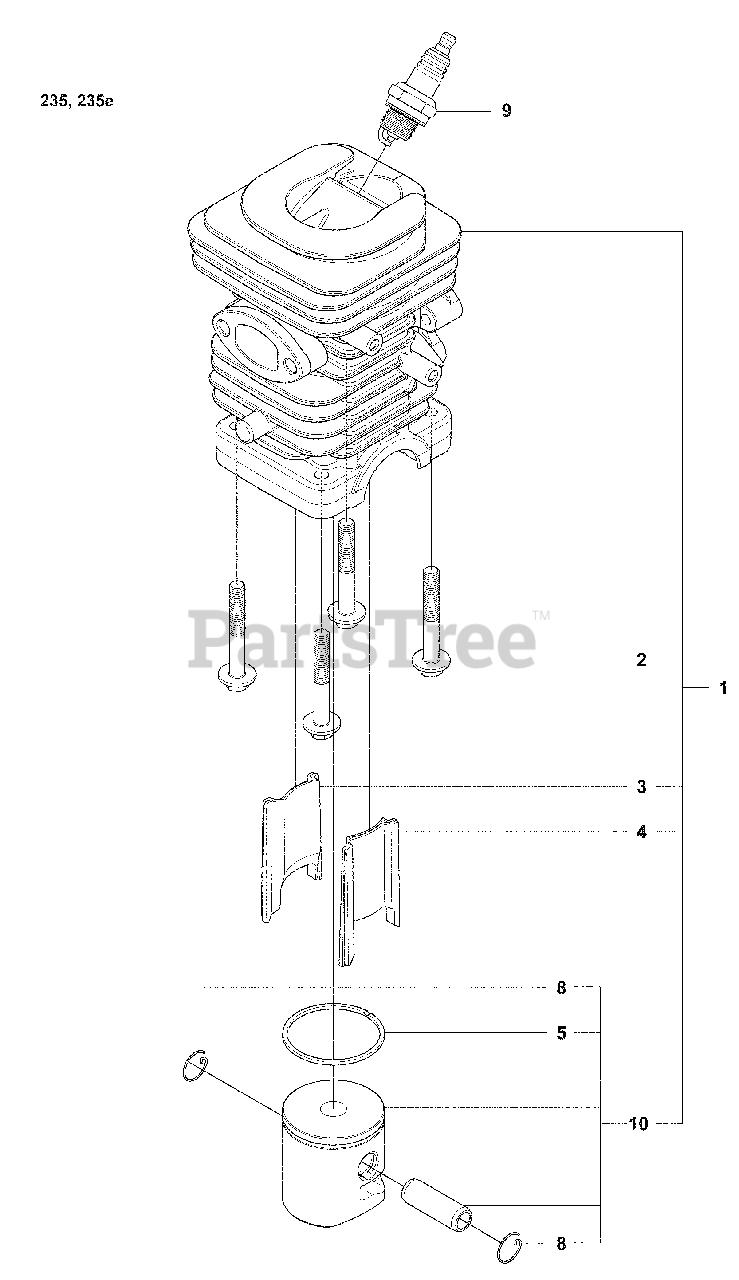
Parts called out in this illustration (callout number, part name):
2	BOLT, CYLINDER
3	TRANSFER INSERT LEFT 34c
4	TRANSFER INSERT RIGHT 34cc
5	PISTON RING
8	PISTON PIN RETAINER
9	PLUG-SPARK (RCJ-7Y)
10	KIT PISTON 34cc 235/235e
11	KIT, CYLINDER & PISTON
